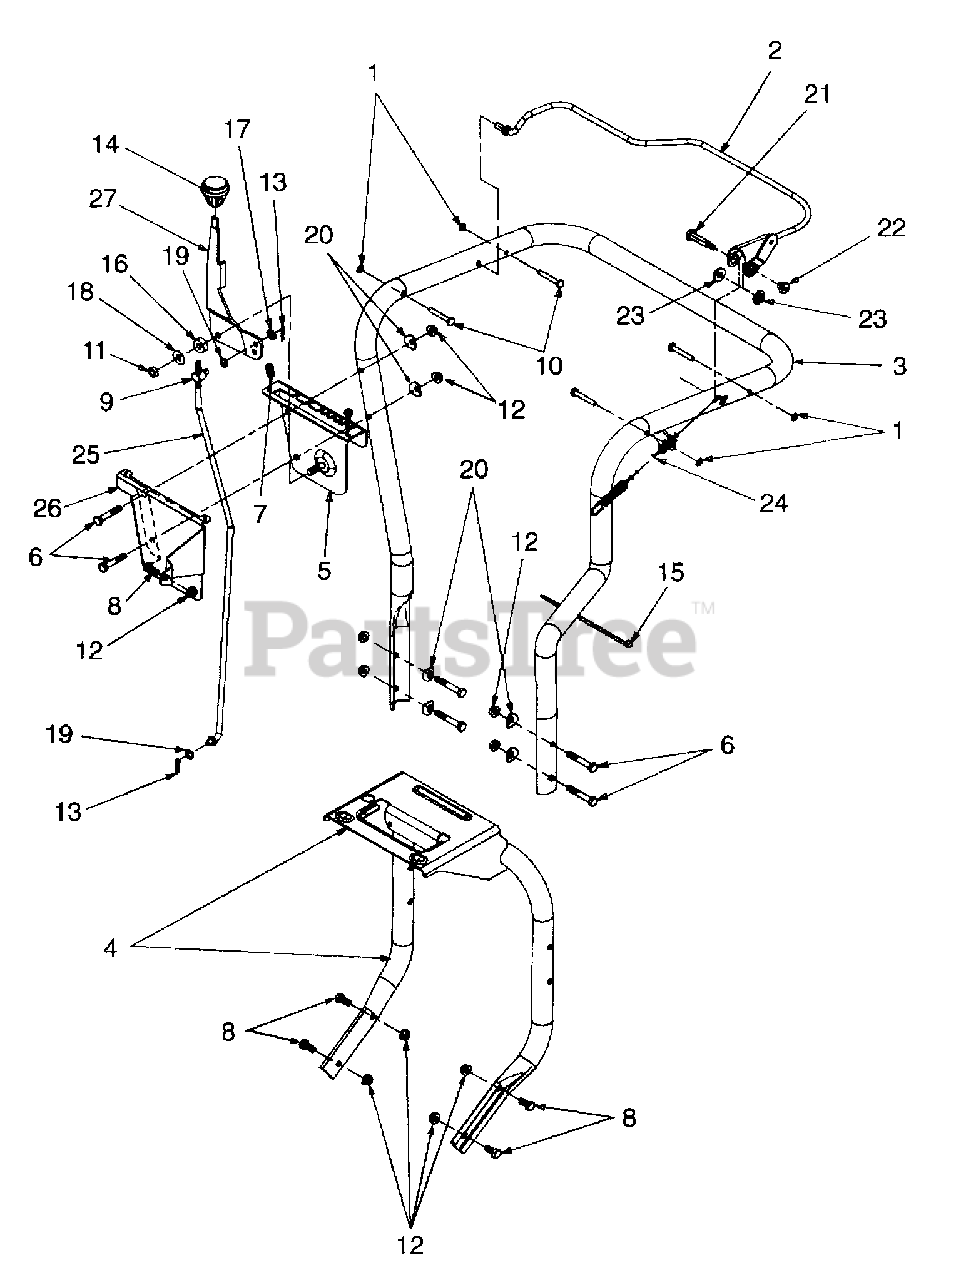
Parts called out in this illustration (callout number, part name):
1	Nut, Push, 25
7	Screw, Hex Wash Hd, 4-14 x .625
8	Screw, Hex Cap 5/16-18 x .75 GR5
9	Ferrule
10	Pin, Stud, .250 x 1.75
11	Nut, Hex Insert Jam Lock 3/8-24.
12	Nut, Hex Flange Lock 5/16-18 GR5
13	Pin, Internal Cotter
14	Knob, Shift
15	Cable Tie
16	Washer, Rubber
17	Washer, Flat, .385 x .62 x .06
18	Washer, Flat, .406 x .875 x .059
19	Washer, Spring, .390 x .62
20	Washer, Saddle, .320 x .93
21	Shoulder Screw, .374 x 1.375
22	Shoulder Nut, 1/4-20
23	Bearing, Hex Plastic Flange
24	Cable, Clutch
25	Rod, Shift
